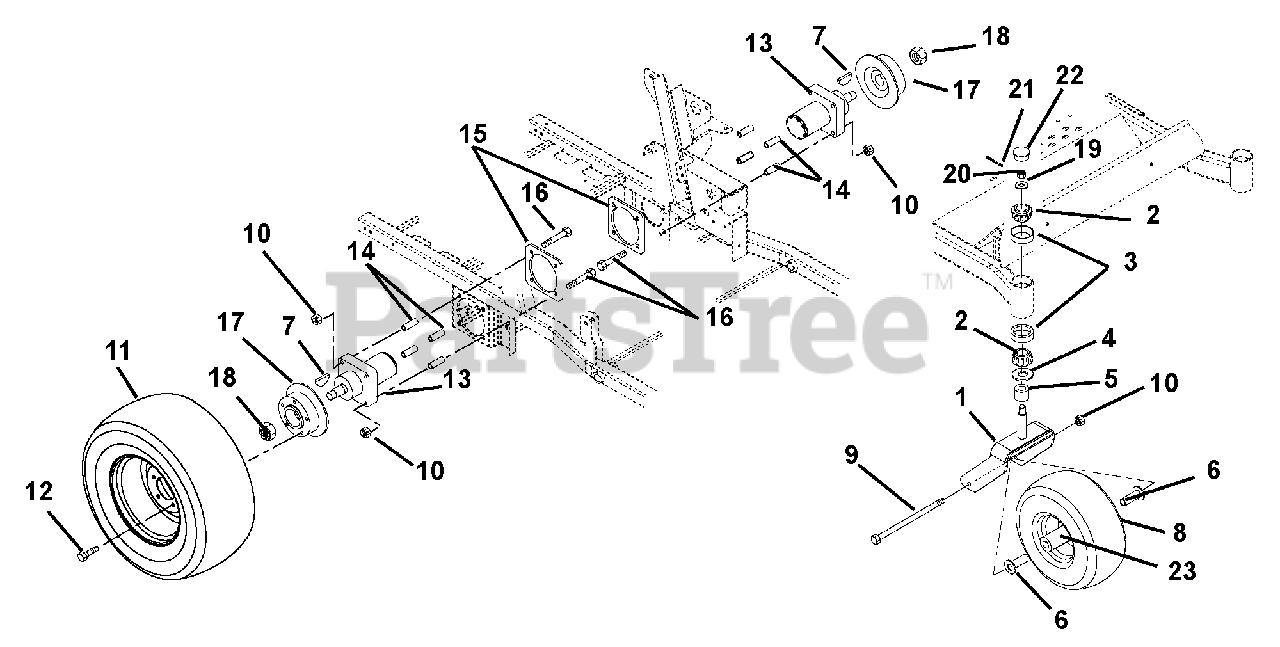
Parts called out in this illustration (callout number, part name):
1	Fork
2	Bearing, Cone with Grease
3	Bearing, Cup 1.98 x .420
4	Bearing Seal 1.5 x 2 x .18
5	Spacer, PM, 1.03 I.D. x 1.5 O.D. x .375
6	Spacer, Wheel
7	Key, Woodruff .31 x 1.00
8	Wheel/Tire Assembly
8	Tire, 15 x 6-6
9	Bolt, Hex .50-13 x 9.00 Grade 5
10	Nut, Locking Top Flange .50-13
11	Wheel, Tire Assembly 23 x 10.50 -12 (992051, 055, 080, 081, 082, 095, 097)
11	Tire 23 x 10.50(992043, 044, 051, 054, 055, 078, 079, 080, 081, 082, 093, 094, 095, 096, 097, 311)
11	Wheel, Tire 23 x 10.50 - 12 Multi-Trac (992043, 044, 054, 078, 079, 081, 093, 094, 096, 311)
11	Wheel, Tire Assembly 23 x 9.50-12 (992042, 064, 077, 083, 092, 310)
11	Tire, 23 x 9.50-12 Multitrac (992042, 064, 077, 083, 092, 310)
12	Bolt, Lug Grade 8 .50-20 UNF x 1.38 Long 60 Degree
13	Hydraulic Wheel Motor
14	Bushing, Sleeve .513 x .748 x 2.13
15	Plate, Motor Support
16	Bolt, Hex .50-13 x 5.00 Grade 5
17	Hub and Disc
18	Nut, Lock Jam Patch
19	Washer, Flat Steel .755 x 1.375 x .062
20	Nut, Slotted .75-16
21	Pin, Cotter .16 x 1.00
22	Cap, Dust
23	Bearing, 25mm I.D. x 52mm OD x 15mm
